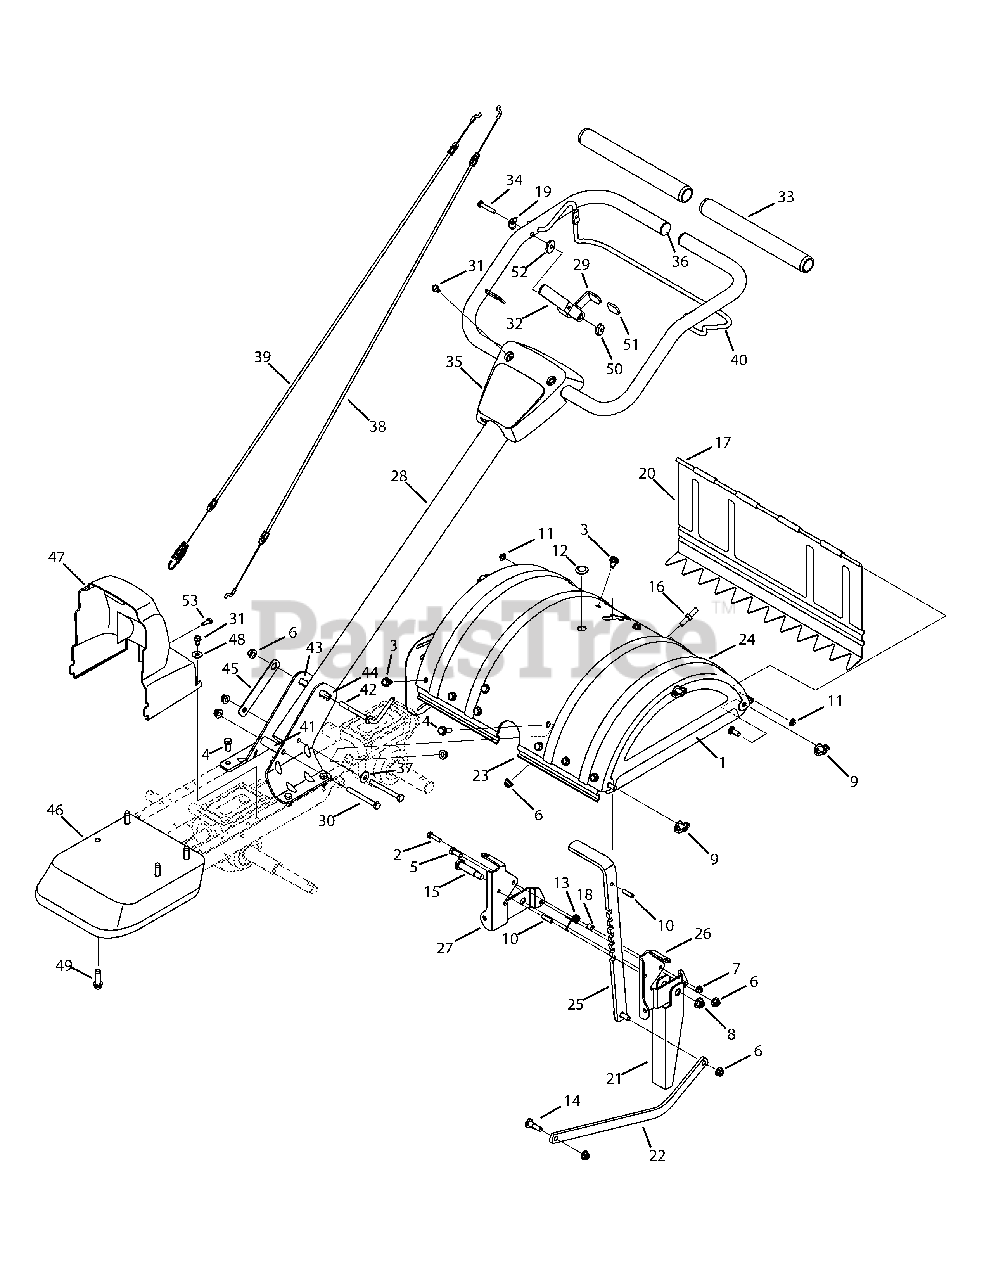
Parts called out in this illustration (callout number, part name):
1	End Cover Assembly
2	Hex Head Screw, 1/4-20 x 1
3	Hex Head Screw, 5/16-18 x 625
4	Hex Head Screw, 5/16-18 x 875
5	Hex Head Screw, 5/16-18 x 75
6	Hex Flange Top L-Nut, 5/16-18
7	Nylon Hex Lock Nut, 1/4-20
8	Flange Lock Nut, 3/8-16
9	Wing Nut, 5/16-18
10	Spirol Pin
11	Cap Nut, 1/4 Rod
12	Hole Plug
13	Torsion Spring
14	Shoulder Screw, 405 x 435 5/16-18
15	Shoulder Screw, 498 x 1635
16	Stop Screw
17	Tiller Flap Rod
18	Spacer
19	Saddle Washer, 320 x 930 x 060
20	Rear Tine Shield
21	Reverse Stop Arm
23	Tine Shield Mounting Bracket
24	Tine Shield
25	Adjustable Depth Bar
26	Tail Bracket, LH
27	Tail Bracket, RH
28	Upper Handle Assembly
29	Reverse Handle Assembly
30	Hex Head Screw, 5/16-18 x 300
31	Self-Tapping Screw, 1/4-20 x 1/2
32	Handle Select
33	Foam Handle Grip
34	Hex Head Screw, 1/4-20 x 162
35	Handle Cover
36	Plug End
37	Bell Washer, 340 x 872 x 060
38	Reverse Cable
39	Forward Cable
40	Clutch Bail
41	Spacer, 322 x 625 x 200
42	Handle Crank
43	Handle Bracket, RH
44	Handle Bracket, LH
45	Retainer Nut Bracket
46	Front Bumper
47	Belt Cover
48	Flat Washer, 28 x 74 x 063
49	SEMS Screw, 3/8-16
50	Spacer, 375 x 165
51	Reverse Handle Grip
52	Flat Washer, 265 x 938 x 120
53	Self Tapping Screw, 1/4-14 x 625
